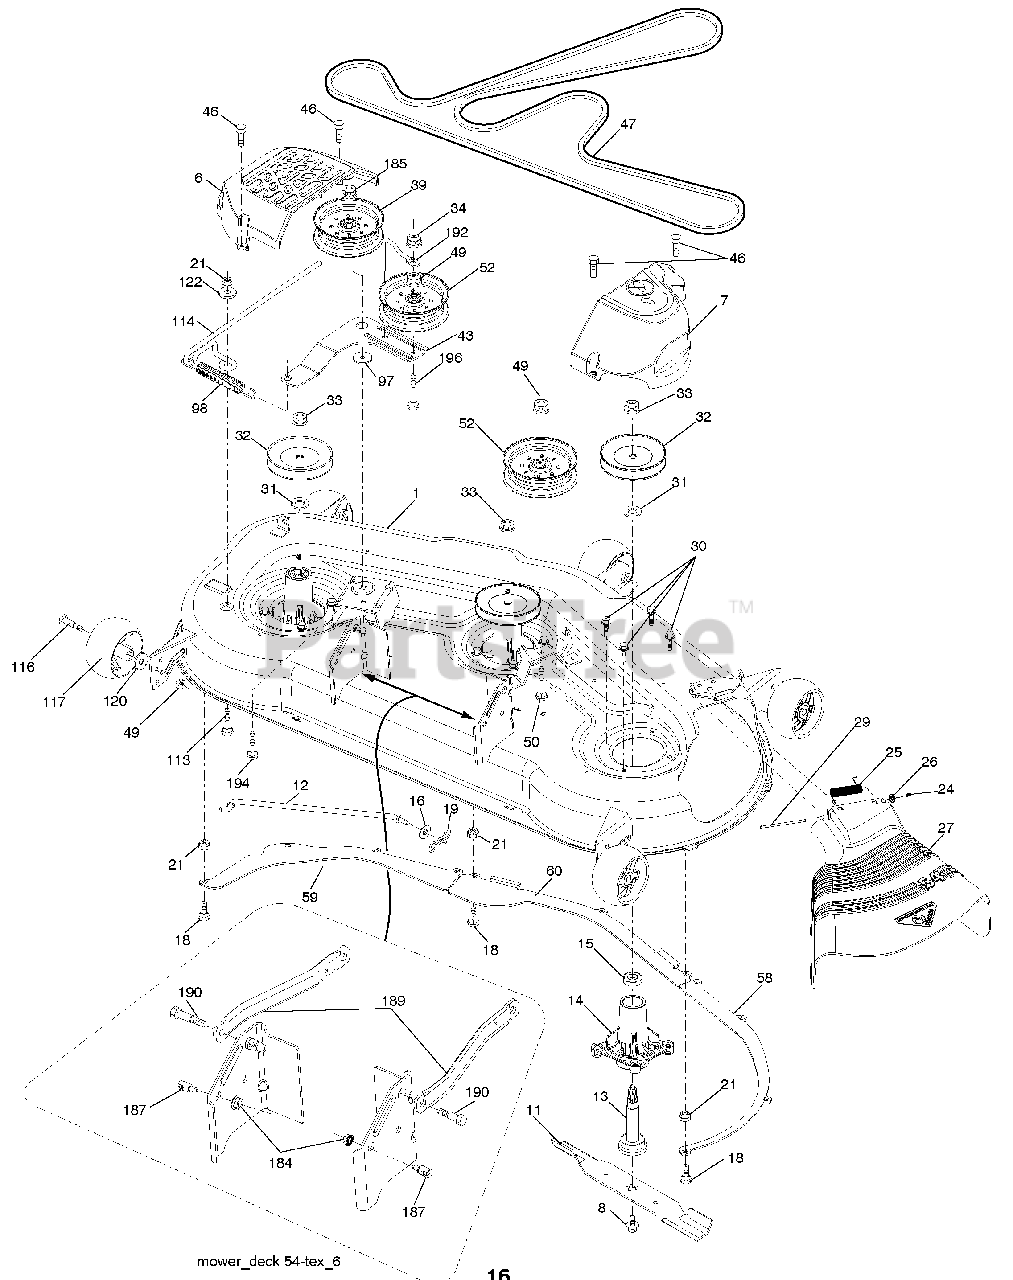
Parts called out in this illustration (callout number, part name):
1	Deck Weldment Mower
6	Cover Mandrel LH
7	Cover Mandrel RH
8	Bolt 7/16 Asm. Blade
11	Blade Discharge
11	Blade Mulching
11	Blade Bagging
12	Rod-Anti Sway
13	Shaft Asm. w/Lower Bearing
14	Housing, Mandrel
15	Bearing, Ball, Mandrel
16	Washer 13/32 x 13/16 x 12 Ga.
18	Bolt 5/16 - 18 x 5/8
19	Pin Cotter 5/16 Bow Tie Lock
21	Nut, Crownlock 5/16-18 unc
24	Cap Sleeve
25	Spring, Torsion
26	Nut, Push
27	Deflector Shield
29	Rod, Hinge
30	Screw, Thdroll Washer Head
31	Washer, Spacer Mower Vented
32	Pulley, Mandrel
33	Nut, Flg. Top Lock
34	Nut Crownlock 3/8-16 unc
39	Pulley, Idler, Stationary
43	Arm, Idler
46	Screw, Thdroll. 1/4-20 x 5/8
47	V-Belt, Mower
49	Nut, Lock Flg. 3/8-16 unc
50	Bolt RDHD SQNK 3/8-16 unc x 2
52	Pulley Idler Clutching
58	Baffle Right
59	Baffle Left
60	Baffle Center
97	Washer Hardened
98	Spring Drive
113	Bolt Rdhd Sqnk 5/16-18 x 3/4
114	Rod Tension Relief
116	Bolt, Shoulder
117	Gauge Wheel
120	Washer 13/32 x 1-1/4 x 12 Ga.
122	Bushing Tension Relief
184	Nut Lock Hex Flange 5/16-18
185	Nut Lock Flange 7/16-14 Gr. 5
187	Stud Fastener w/"D" Anti-Rotation
189	Arm Susp. Mower Rear
190	Bolt Shoulder
192	Keeper Belt Idler
194	Bolt Carr Sqnk 3/8-16 x 2-1/4
196	Bolt Rdhd Sqnk 3/8-16 x 2-1/2 Gr. 5
196	Mandrel Asm. Service
196	Replacement Mower, Complete
